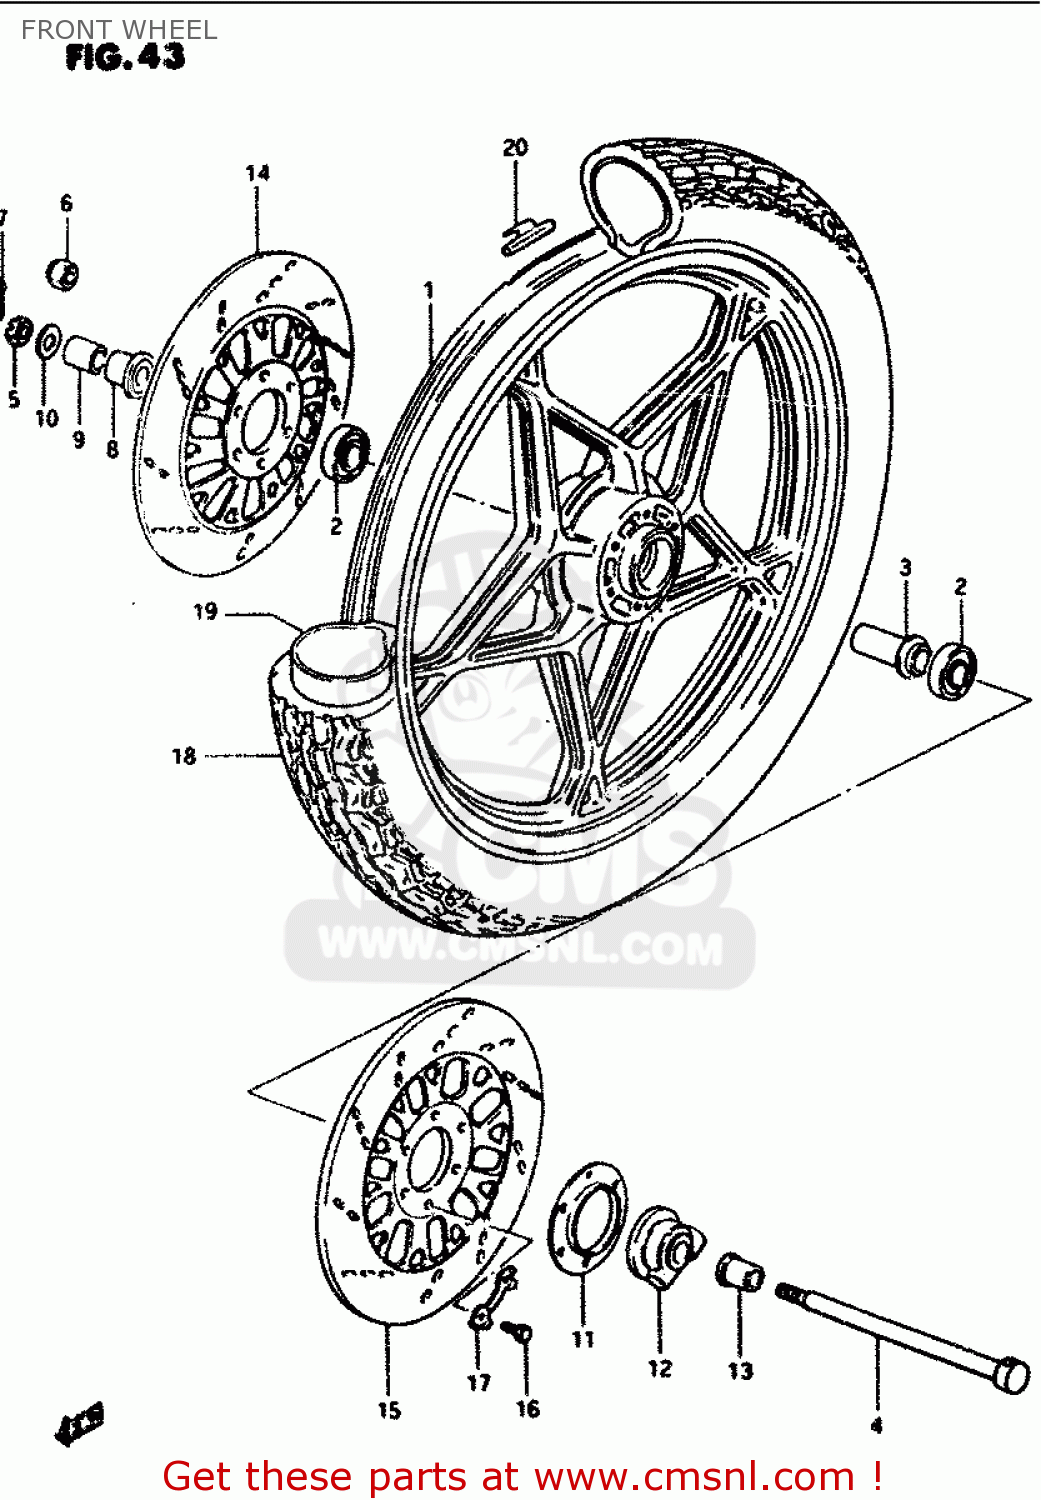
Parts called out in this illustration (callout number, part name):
1	CASTING WHEEL,FRONT 2.15
2	BEARING
3	SPACER,FR HUB BEARING
4	AXLE,FR
5	NUT 12MM
6	NUT
7	COTTER PIN
8	SPACER,FR AXLE,R
9	SPACER,FR AXLE,R
10	WASHER
11	DUST SEAL,SPEEDOMETER GEAR BOX
12	BOX ASSEMBLY,SPEEDOMETER GEAR
13	SPACER,FR AXLE,L
14	DISC,FR BRAKE,R
15	DISC,FR BRAKE,L
16	BOLT(8X25)
17	WASHER
18	TIRE 3.50V19
19	TUBE,INNER
20	BALANCER,WHEEL
